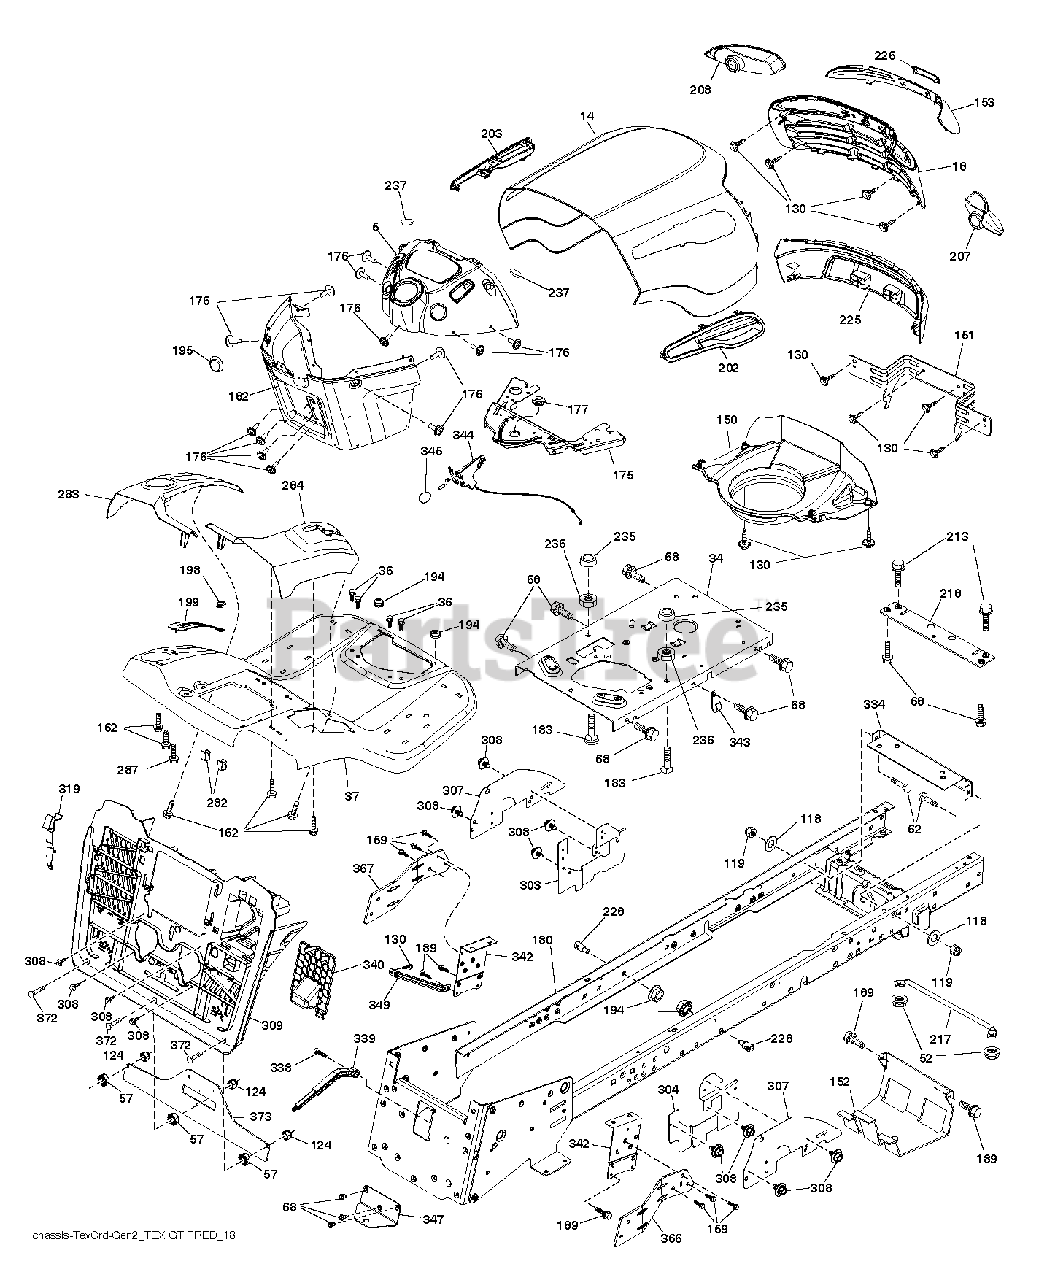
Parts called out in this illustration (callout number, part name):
36	SCREW 5/16"
52	LOCKNUT
57	NUT
119	LOCKNUT
124	LOCKNUT
130	SCREW.#10 X 0.750.BOS THREAD
150	PREDATOR.YT.GT.HOOD.A
152	SHIELD BROWNING
159	SCREW, 3/8-16X3/4
162	SCREW.HI-LO.CONSOLE
175	PLATE.CROSSMEMBER.HUSQ
176	SCREW.#10-24X5/8.RN.QU
177	BUSHING STEERING
180	WELDMENT.CHASSIS.TEX.
183	BOLT.5/16-18X1-1/4 FULL THD
189	SCREW
194	NUT LOCK HEX FLANGE 5/16-18
195	PLUG.HOLE.DASH.LOWER.12V.BLK
198	INDICATOR.DECK.LIFT.RED
213	BOLT
217	ROD.PIVOT.HOOD
218	X-PIECE.HOOD.STOP.NON/
228	STUD.FASTNER.W/ANTI-ROTATE
235	SPACER FENDER
236	NUT.CENTERLOCK.5/16-
237	PLUG.MOUNT.CARGO.BLK
282	CLIP.RETAINER.CONSOLE.LT.HUSQ
304	SHIELD.LWR.RH.LT30DECK.PNT.BLK
308	BOLT, 5/16-18 X 1 3/4
372	RHSNB, 1/4-20 X 1, GR5
373	REINFORCEMENT BACKPLATE. CRD B
